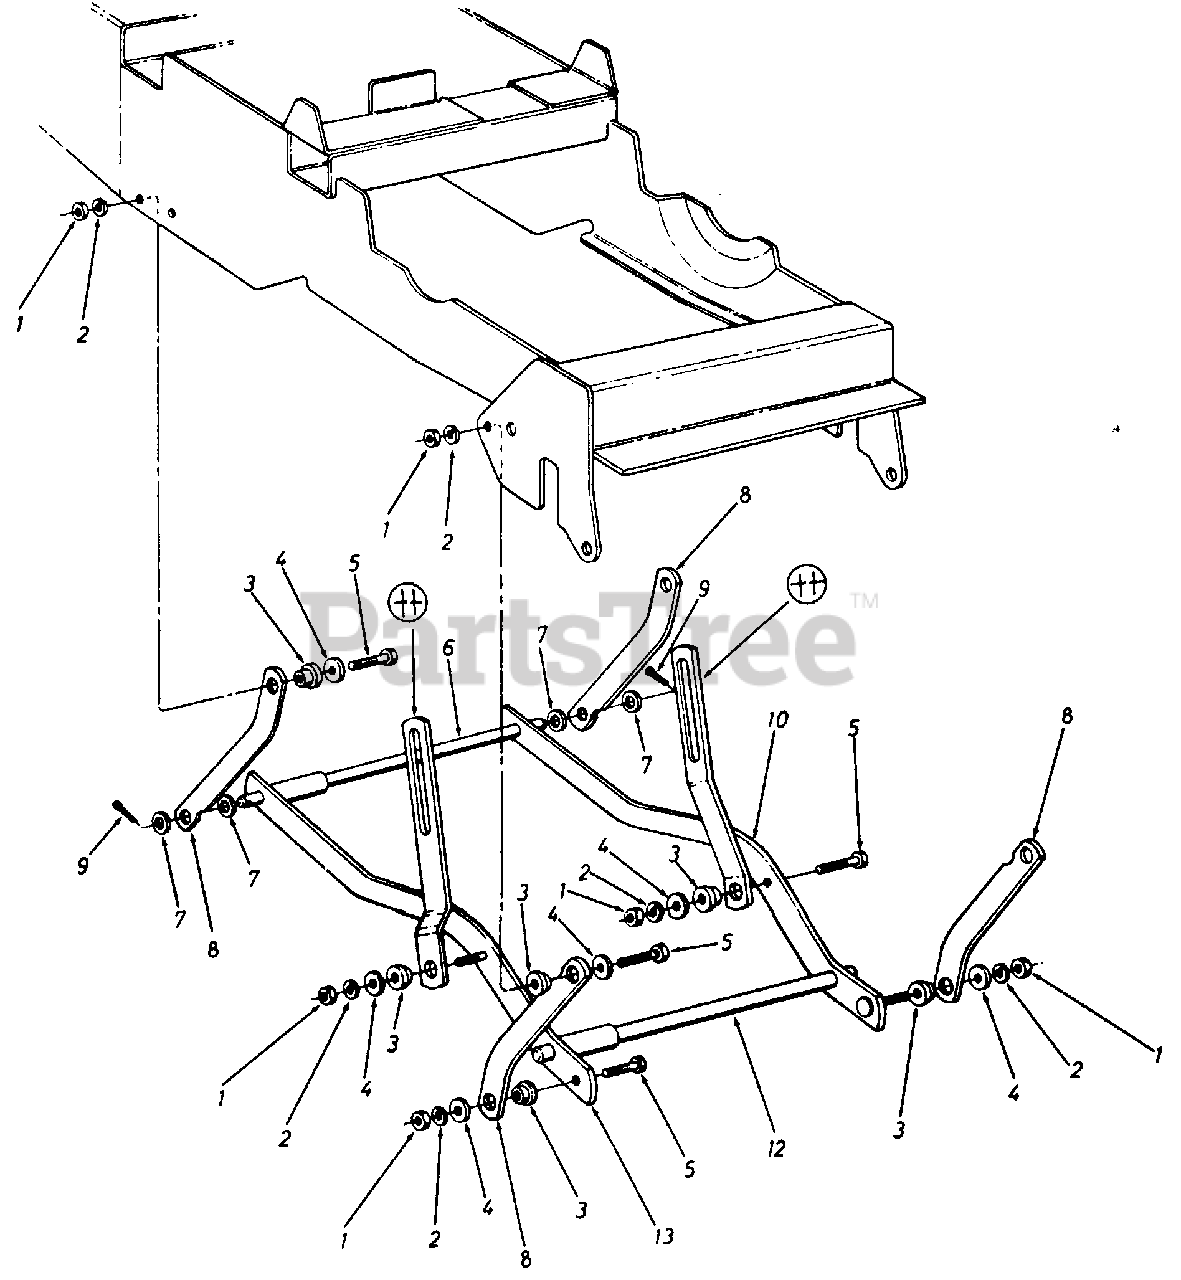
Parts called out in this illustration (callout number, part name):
1	Hex Nut 3/8-24 Thd.*
2	L Wash. 3/8" Scr. Heavy Duty*
3	Shoulder Spacer
4	Fl.-Wash. 3/8"I.D. x 1.0" O.D.
5	Hex Scr. 3/8-24 x 1.50" Lg. Grade 5
6	Cross Shaft Ass'y.-Rear
7	Fl. Wash. 5/8" I.D. x 1-1/8" O.D.
8	Lift Arm
9	Cotter Pin 5/32"Dia, x1.25"Lg.*
10	Lift Arm Link Ass'y.-LH.
12	Cross Shaft Ass'y.-Front
13	LiftArm Link Ass'y. R.H.
